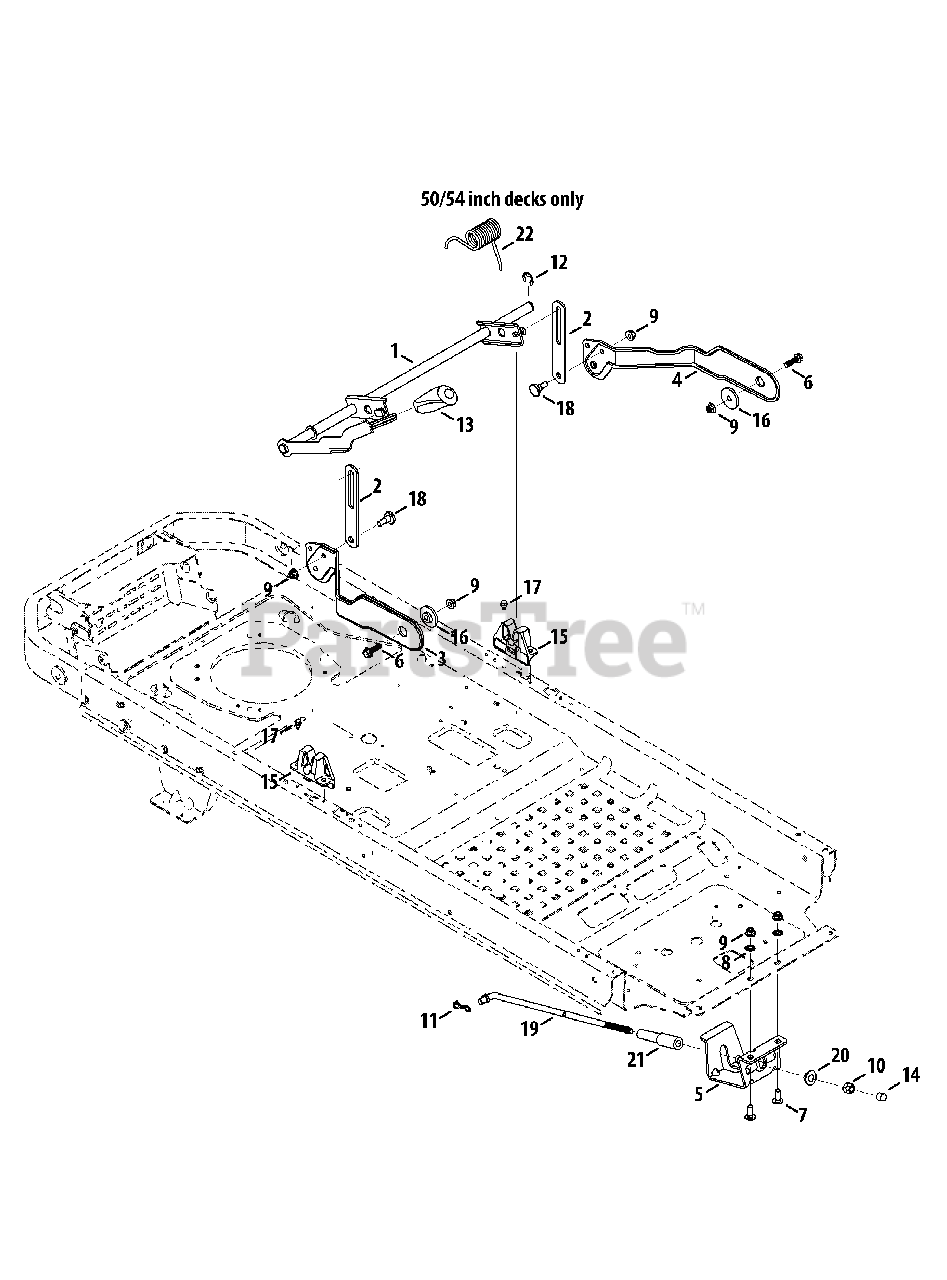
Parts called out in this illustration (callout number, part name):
1	Deck Lift Shift Assembly
2	Lift Link Plate
3	Deck Lift Plate, RH
4	Deck Lift Plate, LH
5	Rod Support Mounting Bracket
6	Hex Washer Screw, 3/8-16 x 1.250
7	Carriage Bolt, 3/8-16 x 1.00
8	Push Nut, 3/8
9	Flange Lock Nut, 3/8-16
10	Flange Lock Nut, 1/2-13
11	Bow-Tie Cotter Pin
12	E-Type Ring, .750
13	Grip, .50 ID
15	Deck Lift Bracket
16	Shoulder Spacer, .884 x .190
17	Shoulder Screw, .500 x 1/4-20
18	Shoulder Screw, .500 Dia. x .434
19	Deck Lift Rod
20	Deck Lift pivot Cup
21	Nylon Sleeve, .55 ID x 4.50 LG
22	Torsion Spring, 1.323 ID x 2.83 LG
